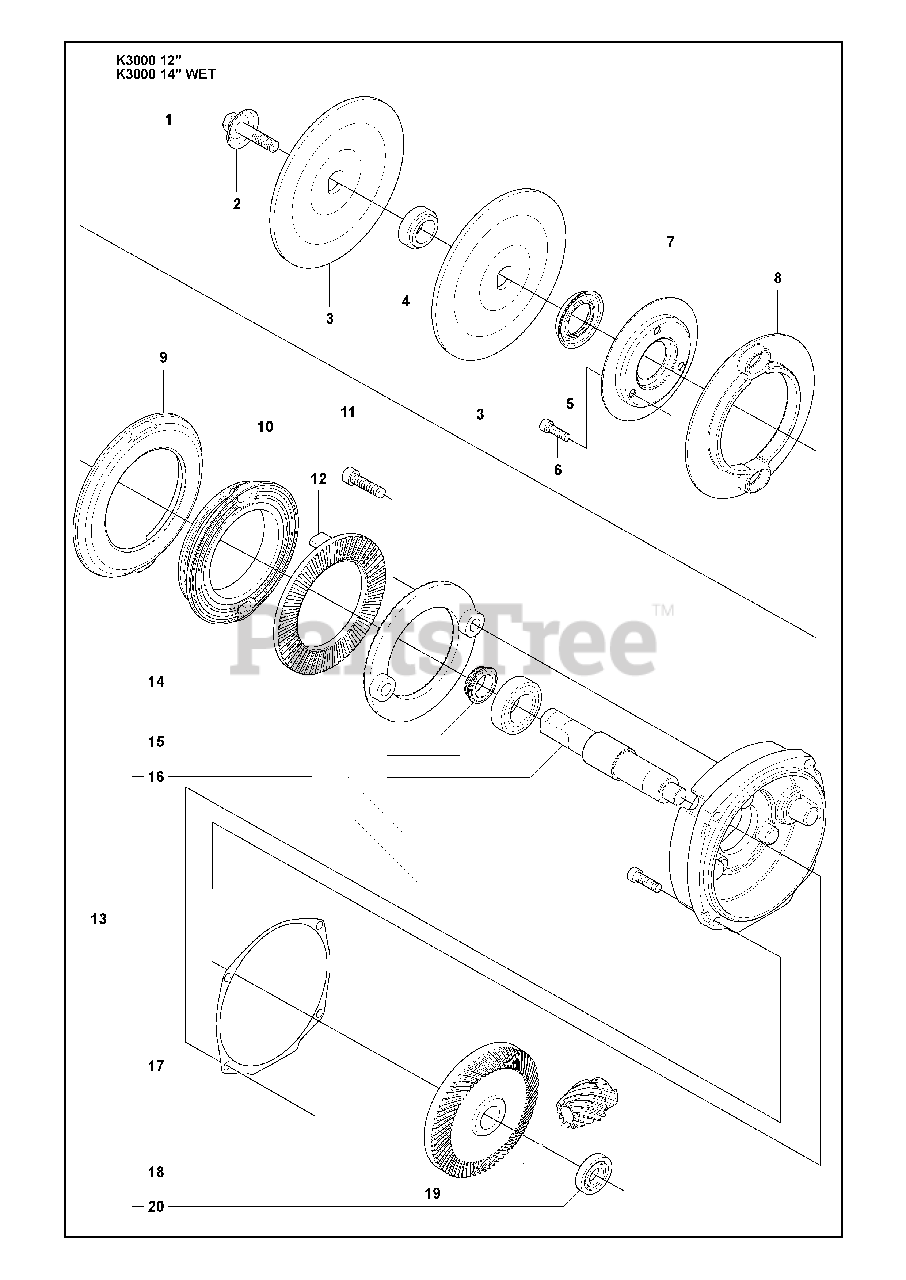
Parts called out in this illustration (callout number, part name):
1	Collar Screw
2	Washer
3	Flange Washer
8	Spacer Ring Inner
9	Spacer Ring Outer
12	Screen Pattern Flang
13	Gear Set
14	Screen Pattern Flang
15	Shaft
17	Gasket
18	Gear Wheel
20	Ball Bearing
